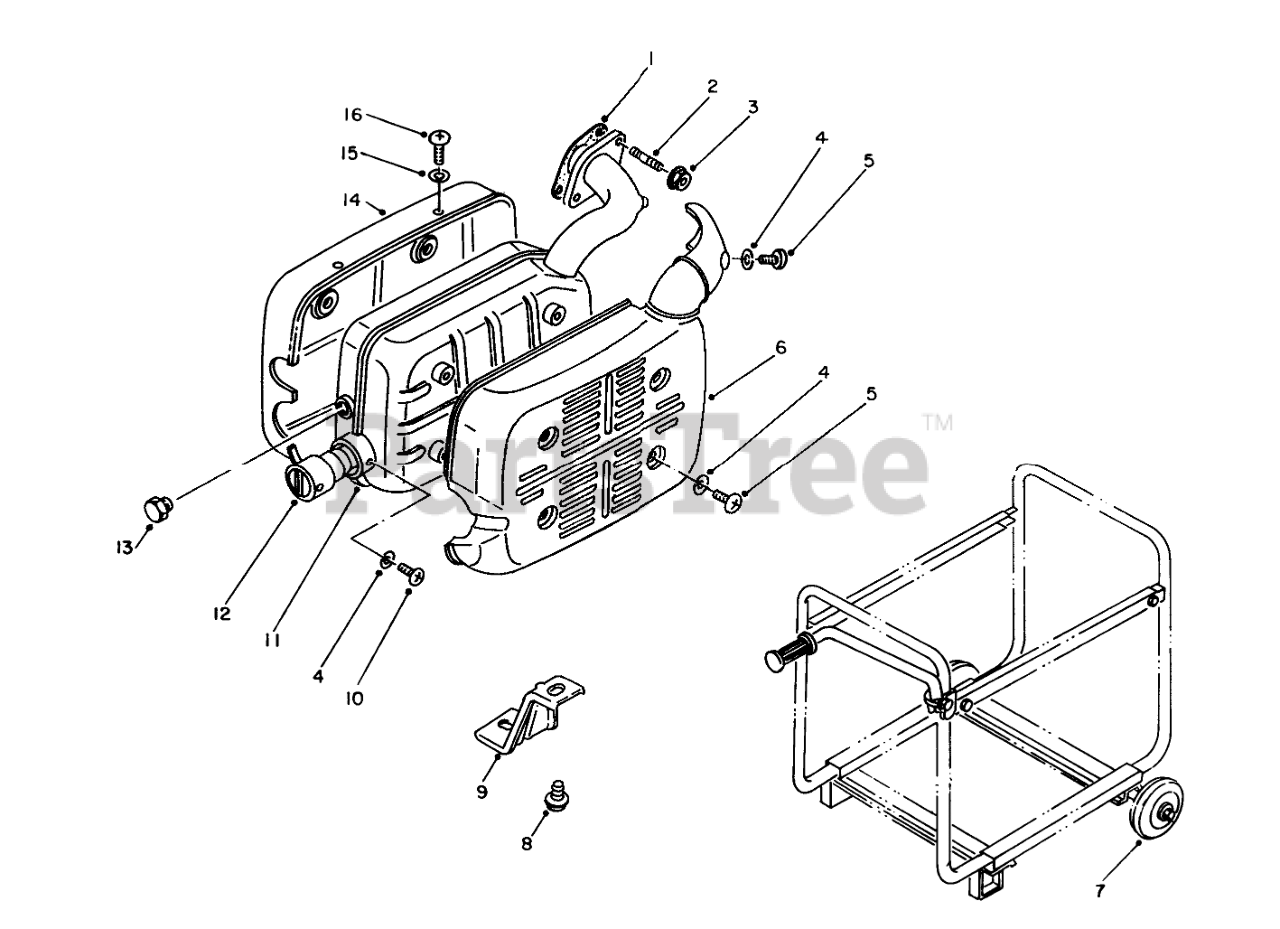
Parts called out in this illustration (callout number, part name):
1	EX GASKET
2	Stud Bolt
4	LOCKWASHER
5	SCREW
6	Cover-Front
7	Wheel Assembly (Optional)
9	Bracket Muffler
10	Screw
11	MUFFLER ASM
12	Cleanout Tube
13	Drain Plug
14	Cover-Rear
15	Lockwasher
16	Screw
